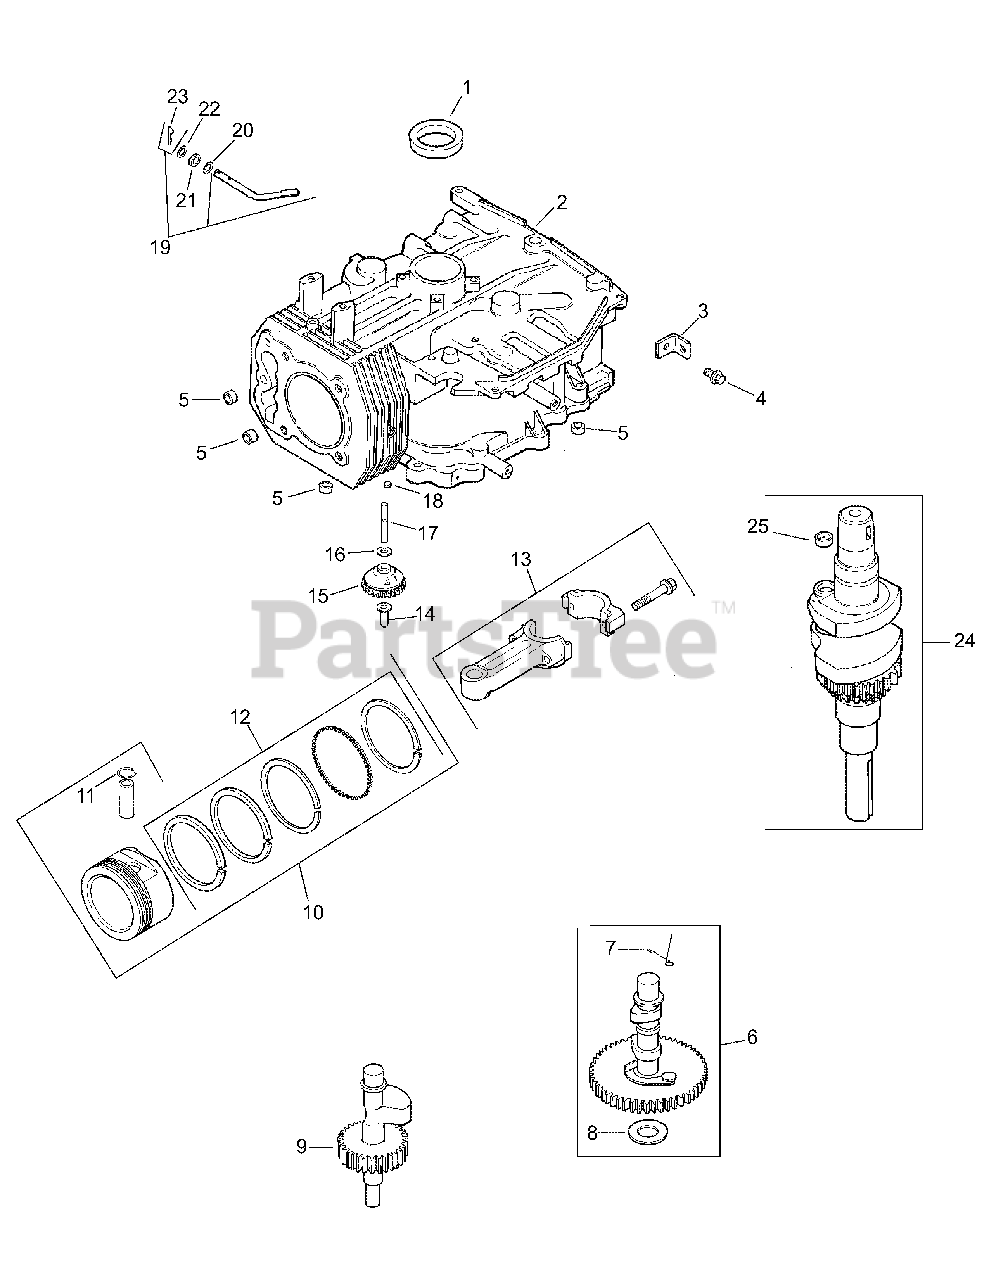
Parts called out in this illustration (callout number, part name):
1	Seal, Crankshaft
2	Crankcase (Short Block)
3	Strap, Lifting
4	Screw, Hex. Flange M8 X 1.25 X 25
5	Pin, Locating
6	Kit, Camshaft (Includes 7, 8)
7	Spring, Actuating
8	Shim, Camshaft - Blue
8	Shim, Camshaft - Red
8	Shim, Camshaft - Yellow
8	Shim, Camshaft - Green
8	Shim, Camshaft - Gray
8	Shim, Camshaft - Black
8	Shim, Camshaft - White
9	Shaft, Balance
10	Piston w/ Ring Set (Std.) (Includes 11, 12)
10	Piston w/ Ring Set (.25)
10	Piston w/ Ring Set (.50)
10	Piston w/ Ring Set (.08)
11	Retainer, Piston Pin
12	Ring Set (Std. & .08)
12	Ring Set (.25)
12	Ring Set (.50)
13	Connecting Rod (Std.)
14	Pin, Governor Regulating
15	Gear, Governor
16	Washer, Plain 6 Mm
17	Shaft, Governor Gear
19	Kit, Governor Cross Shaft w/clip (Incl. 23)
20	Washer, Plain 1/4"
21	Seal, Governor Cross Shaft
22	Washer, Plain 6 Mm
23	Clip, Hitch Pin
24	Crankshaft (Includes 25)
